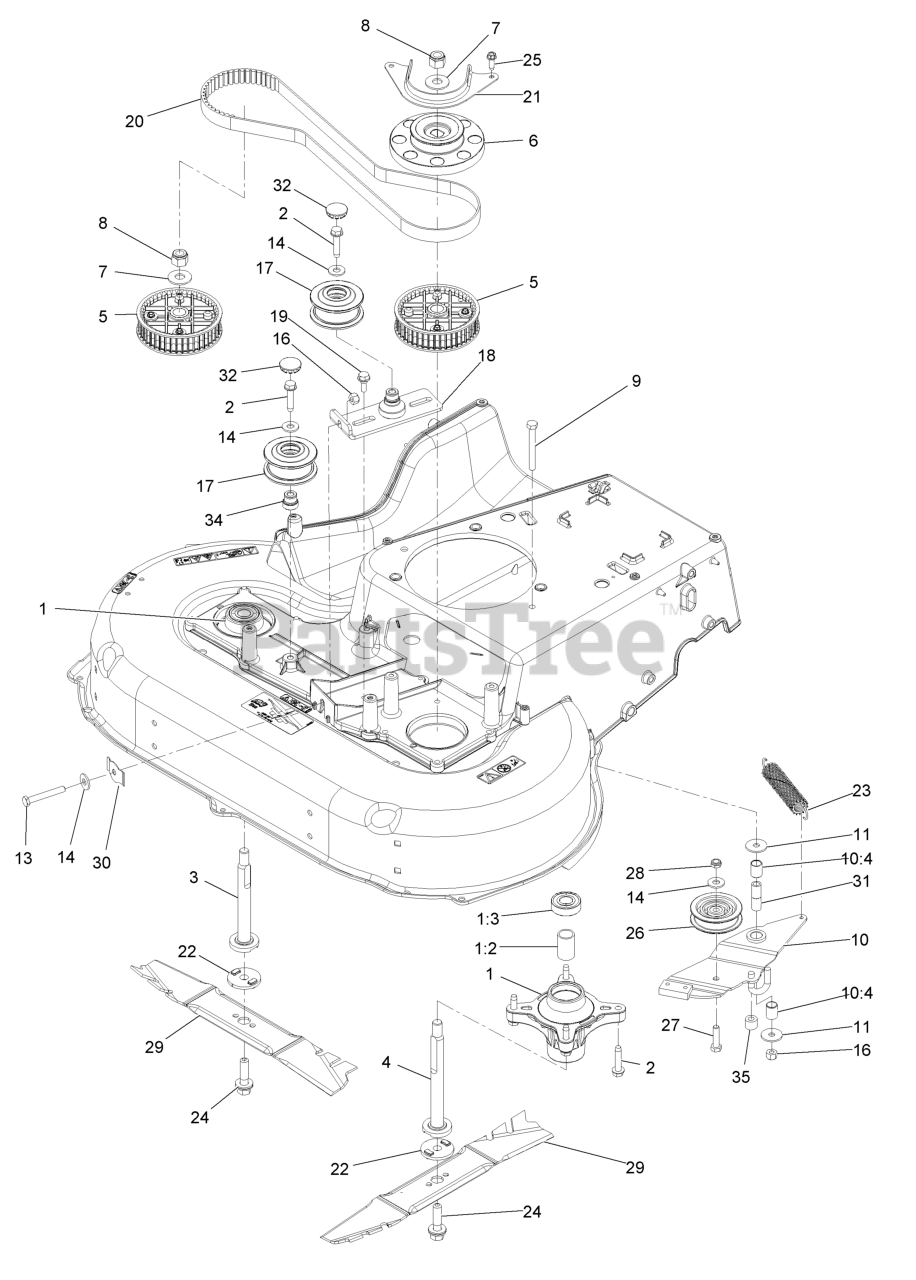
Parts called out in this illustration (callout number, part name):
1	Spindle ASM
1:3	Bearing-Ball
2	Screw-HWH
3	Shaft-Spindle
4	Shaft-Spindle
5	Sprocket
6	Pulley-Brake, Spindle
7	Washer, Spring Disc 1/2
8	Nut-Nyloc 1/2-20
9	Screw-HH 5/16-18 X 2 3/4
10	Brake Arm ASM
10:4	Bushing-Sleeve
11	Washer-Pivot
13	Bolt-HH 5/16-18 X 2 1/4 Tap
14	Washer-5/16 Std
16	Nut-Nyloc 5/16-18
17	Pulleys And Idler Kit
18	Bracket-Idler
19	Screw-HH Flg 1/4-20 X 3/4 Tf
20	Belt-Synchronous
21	Guide-Belt, Spindle
22	Adapter-Blade
23	Spring-Extension, Brake
24	Bolt-Blade
25	Screw-HWH 1/4-20 X 3/4 Tf
26	Pulley-Idler
27	Screw-HH 5/16-18 X 1 1/4
28	Nut-Nyloc 5/16-18 Thin
29	Blade-Rotary
30	Spring-Flat
31	Spacer-Brake
32	Plug-Button
34	Adapter-Bore
35	Hose-Coolant
